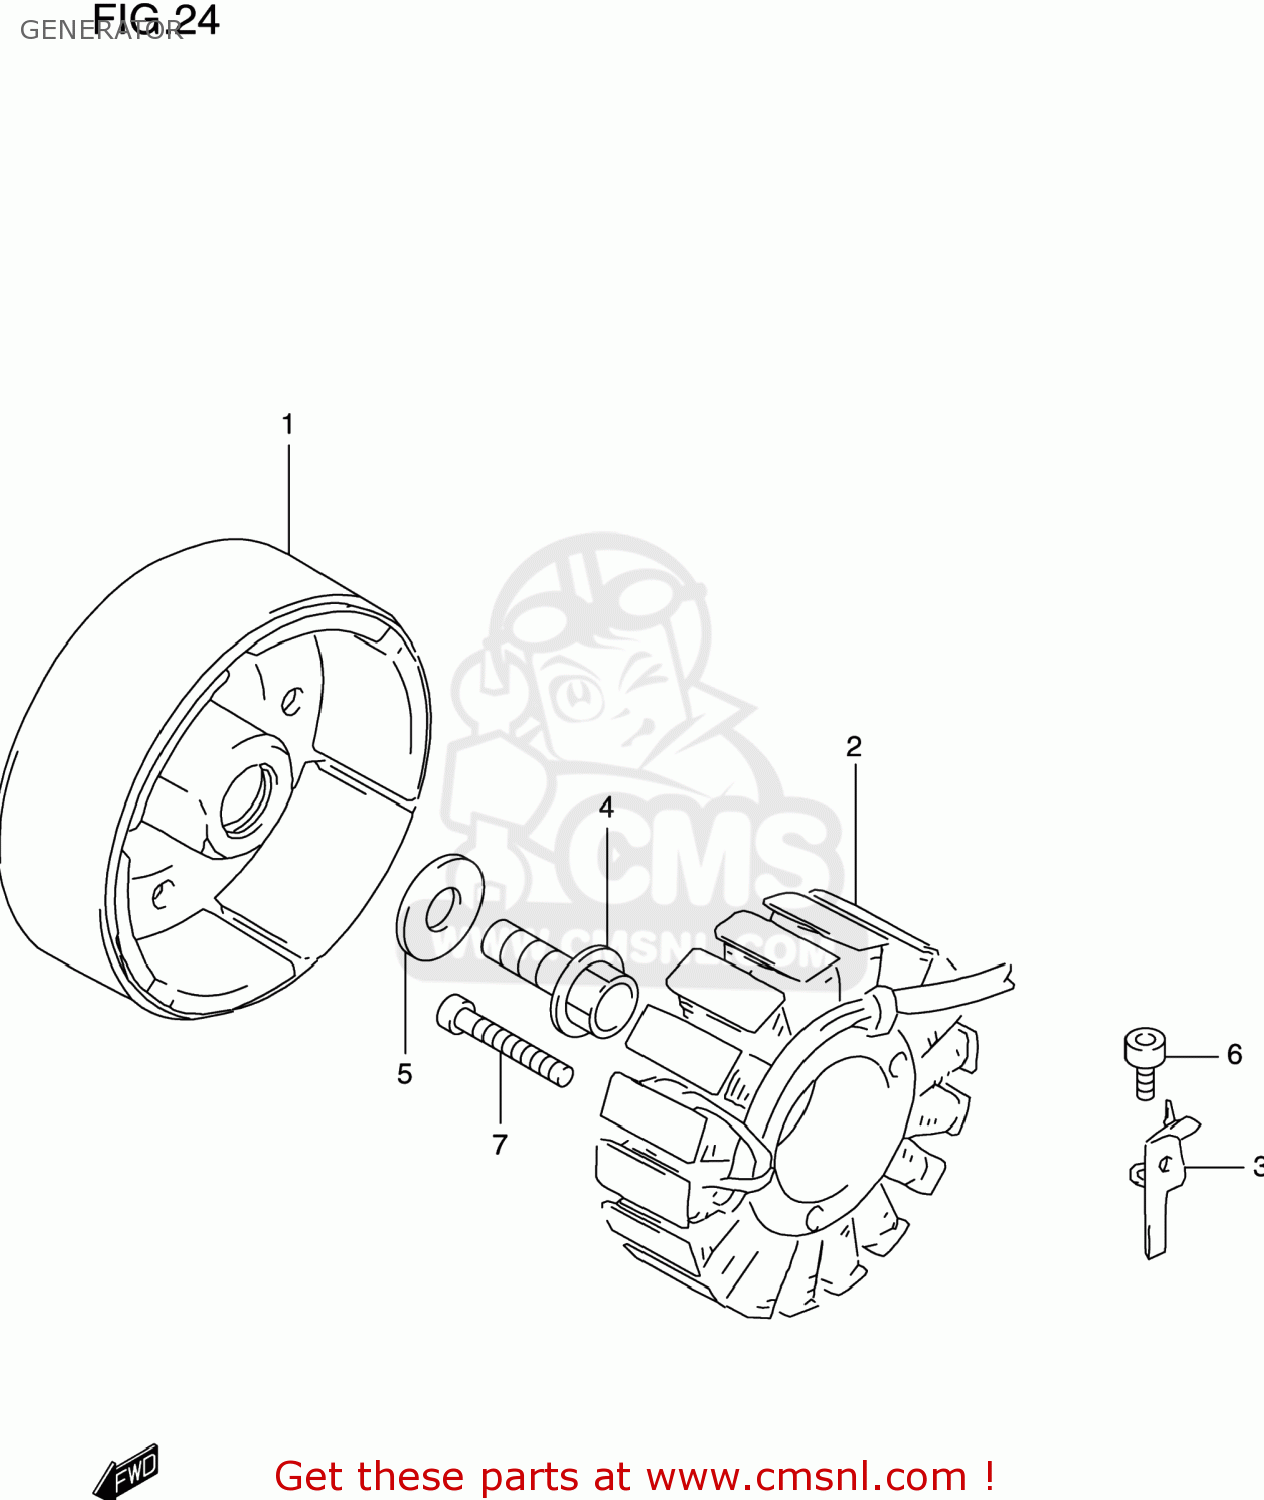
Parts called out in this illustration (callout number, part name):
1	ROTOR ASSY
2	STARTER ASSY
3	CLAMP,MAGNETO LEAD
4	BOLT(12X30)
5	WASHER(12X30X3)
6	BOLT,VAC.PIPE
7	BOLT
